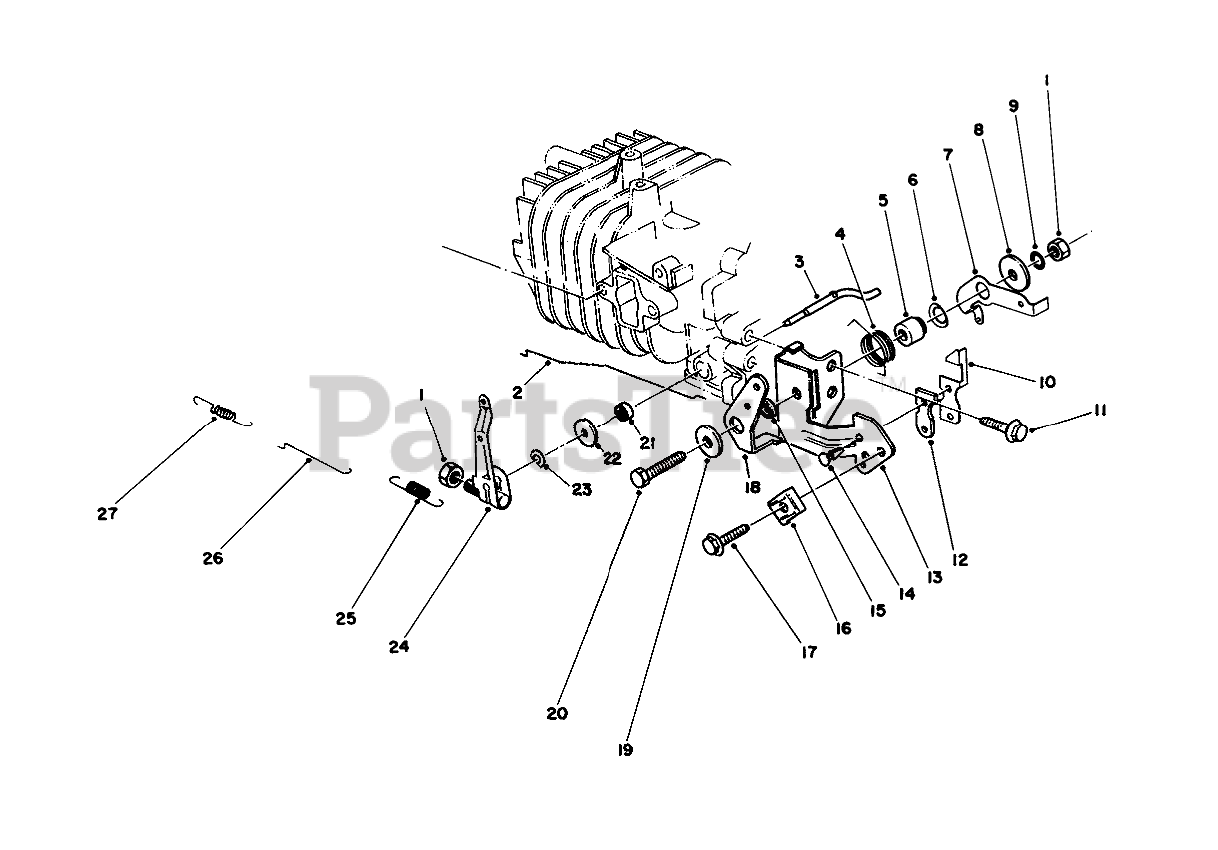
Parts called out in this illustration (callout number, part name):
2	CHOKE ROD
3	Shaft-Govemor
4	SPRING-CHOKE LEVER
5	Gov Lever Spacer
6	Washer-Gov. Spring Lever
7	LEVER-SPRING, GOVERNOR
8	WASHER
9	LOCKWASHER
10	TERMINAL-KILL SWITCH
12	INSULATOR-KILL SWITCH
13	BRACKET-THROTTLE, CONTROL
14	KILL SWITCH RIVET
15	SPACER-CHOKE LEVER
16	CLAMP
18	LEVER-CONTROL, CHOKE
19	WASHER
21	SEAL-OIL
22	WASHER
23	E-RING
24	GOVERNOR ARM
25	SPRING-GOVERNOR
26	ROD-CARBURETOR
27	SPRING
